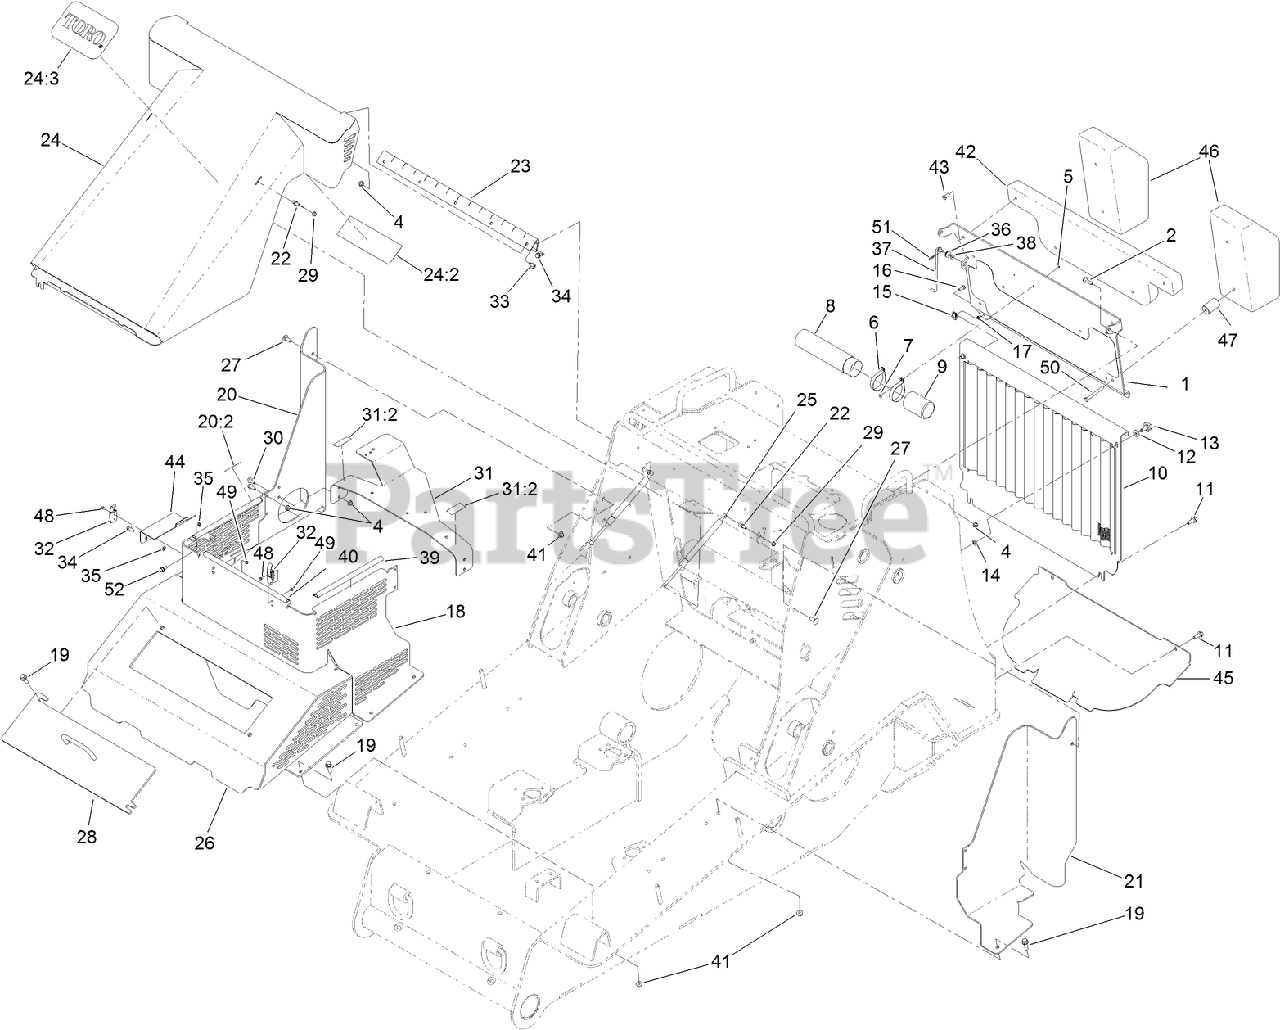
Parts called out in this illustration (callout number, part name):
1	PANEL-REAR
2	SCREW-SHOULDER
4	NUT-HF, NI
5	RIVET-POP
6	CLAMP-R
7	WASHER-BACK
8	TUBE-MANUAL
9	CAP-HOUSING
10	COVER-REAR
11	SCREW-HHF
12	WASHER-RUBBER
14	NUT-PUSH
16	SCREW-HH
17	NUT-RETAINING
18	PANEL-ENGINE
19	SCREW-HHF
20	COVER-GRILLE, RH
20:2	DECAL-SURFACE, HOT
21	PLATE-GRILLE, LH
22	STUD-BALL
23	HINGE-PIANO
24	HOOD ASM
24:2	DECAL-SERVICE
24:3	DECAL
25	CYLINDER-GAS
26	FRONT COVER ASM
27	BOLT-CARR
28	COVER PLATE ASM
29	NUT-LOCK, NI
30	SCREW-HHF
31	BRACKET-AIR CLEANER
31:2	DECAL-SURFACE, HOT
32	LATCH-DRAW
33	SCREW-HHF
34	SCREW-HWH
35	RING-RETAINING, BOLT
36	GROMMET-RUBBER
37	ROD-PROP
38	WASHER-FLAT
39	LINER-FOAM
40	LINER-FOAM
41	NUT-HF, NI
42	CUSHION-PAD
43	SCREW-HH
44	COVER-ACCESS
45	COVER-ACCESS, BOTTOM
46	PAD-REAR
47	SPACER-PAD
48	SCREW-HHF, SERRATED
49	NUT-LOCK
50	SCREW-HH
52	SCREW-HWHTF
